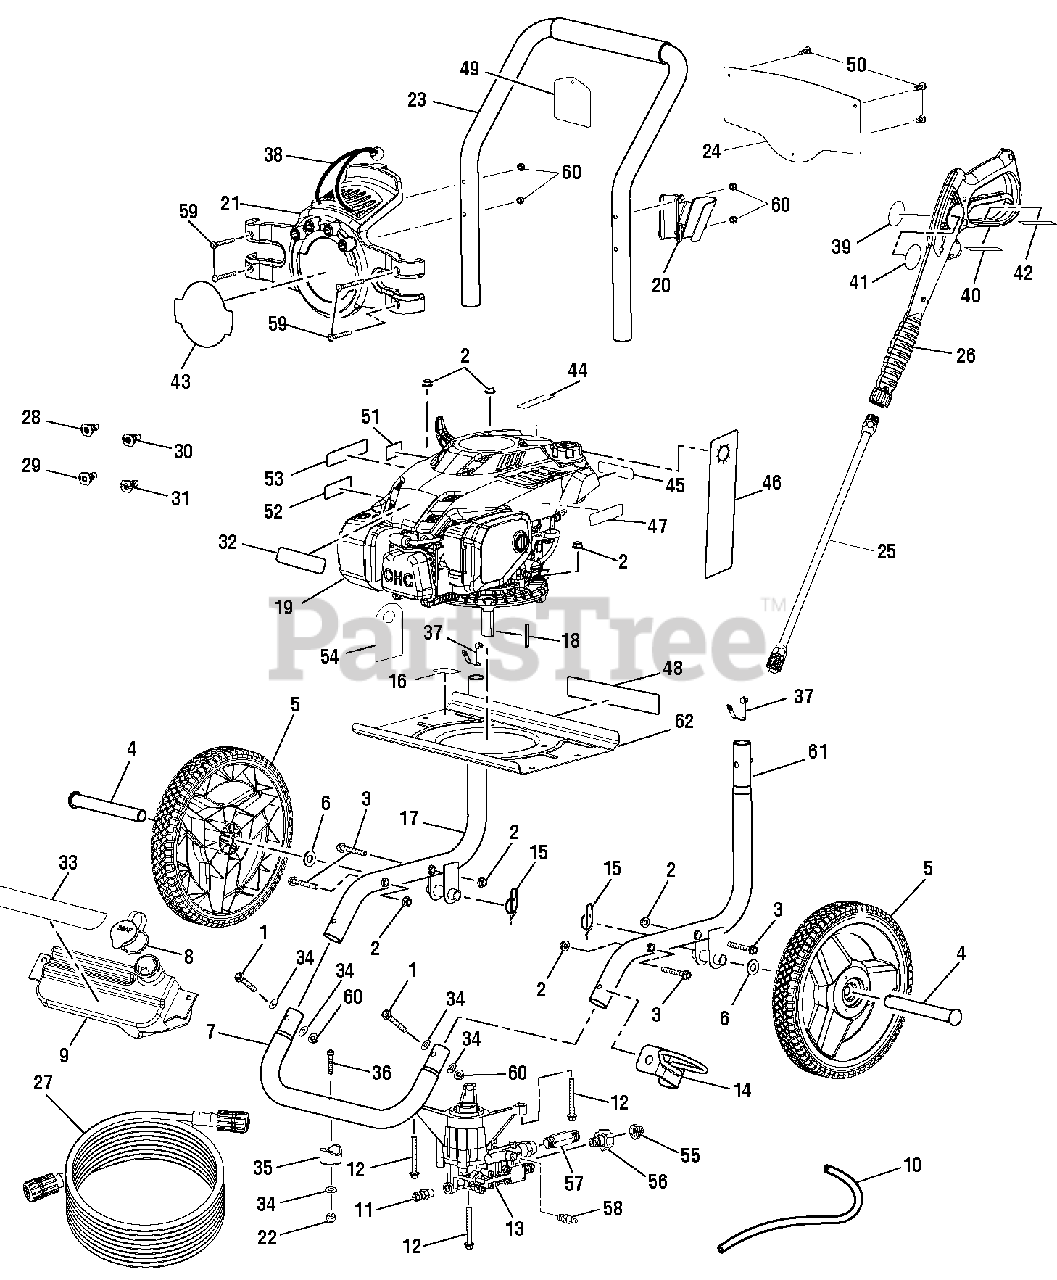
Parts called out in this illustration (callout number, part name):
1	Screw (1/4-20 x 2 in., T30 Torx Hd.)
2	Flange Nut (M8 x 1.25 in.)
3	Bolt (M8 x 55 mm)
6	Washer (1/2 in.)
7	Front Frame Assembly
8	Soap Tank Cap
9	Soap Tank
10	Chemical Siphon Tube
11	Thermal Release Valve
12	Bolt (M8 x 60 mm, Flange Hd.)
13	Pump
14	Wand Holder Loop
15	Ring Clip
16	Engine Plate
17	Main Frame Assembly
18	Output Shaft Key (35mm)
19	Engine (Subaru 190V)
20	Wand Holder
21	Hose and Nozzle Assembly
22	Lock Nut (1/4-20)
23	Handle w/Foam
24	Quick Start Panel
25	Spray Wand Assembly
26	Trigger Handle Assembly
27	Hose (25 ft.)
28	Soap Nozzle
29	25deg Nozzle
30	40deg Nozzle
31	0deg Nozzle
32	Subaru Label
33	Detergent Tank Label
34	Washer (1/4 in.)
36	Screw (1/4-20 x 1.85 in., T30 Torx Hd.)
37	Spring Clip
38	Bungee Cord Assembly
39	Label (Trigger Handle Logo)
40	Label (Trigger Handle Specifications)
41	Label (Trigger Handle Warning)
42	Label (Trigger Handle Warning, French & Spanish)
43	Inquiries Label
44	E85 Label
45	Do Not Mix Label
46	Warning Hangtag
47	Engine Start Label
48	Data Label
49	Nozzle Hangtag
50	Release Water Label
51	Lubricant Label
52	Hot Surface Label
53	Combustion Label
54	Oil Cap Hangtag
55	Oil Fill Location Label
56	Performance Label
57	Screw (M3 x 5 in.)
58	Filter Screen
59	Outlet Tube
60	Inlet Tube
61	Detergent Suction Kit
